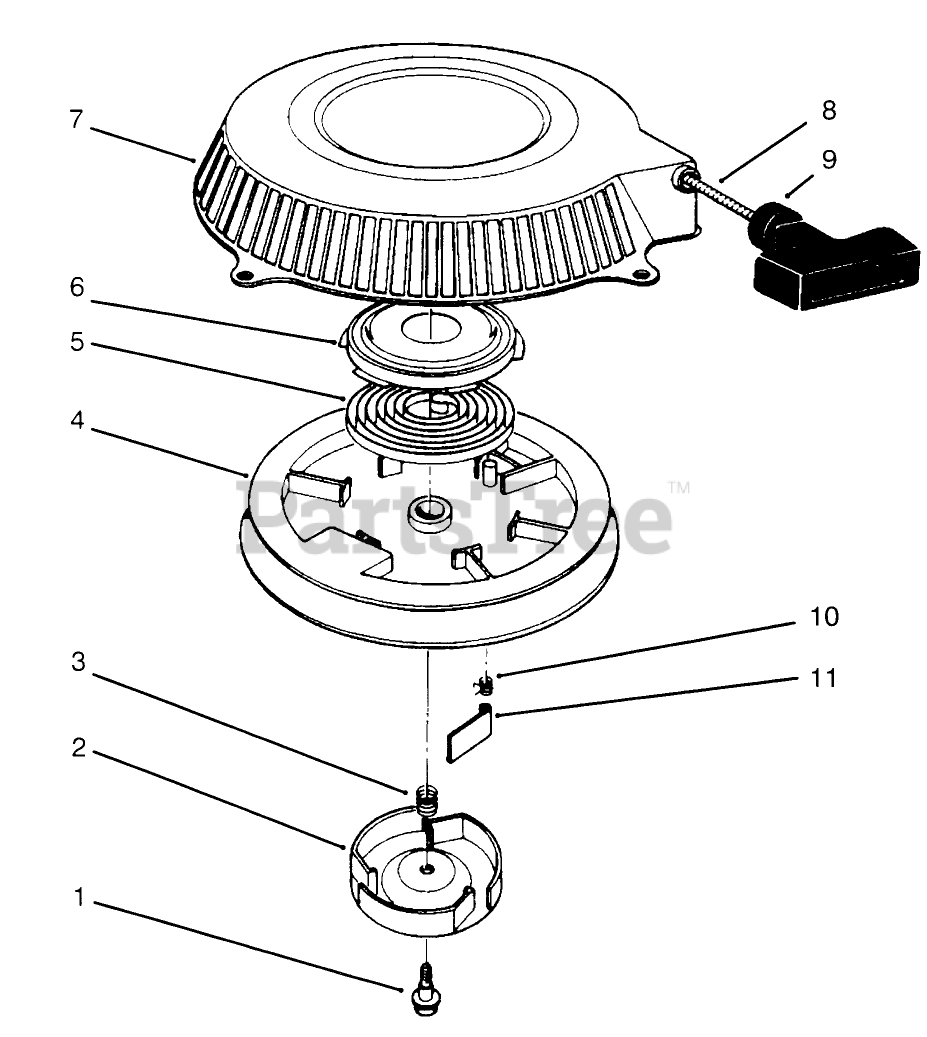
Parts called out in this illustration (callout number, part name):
1	Bolt
2	Retainer
3	Spring
4	Reel
5	Spring
6	Case
7	Case
8	Rope
9	Grip
10	Spring-RETURN
11	Pawl
